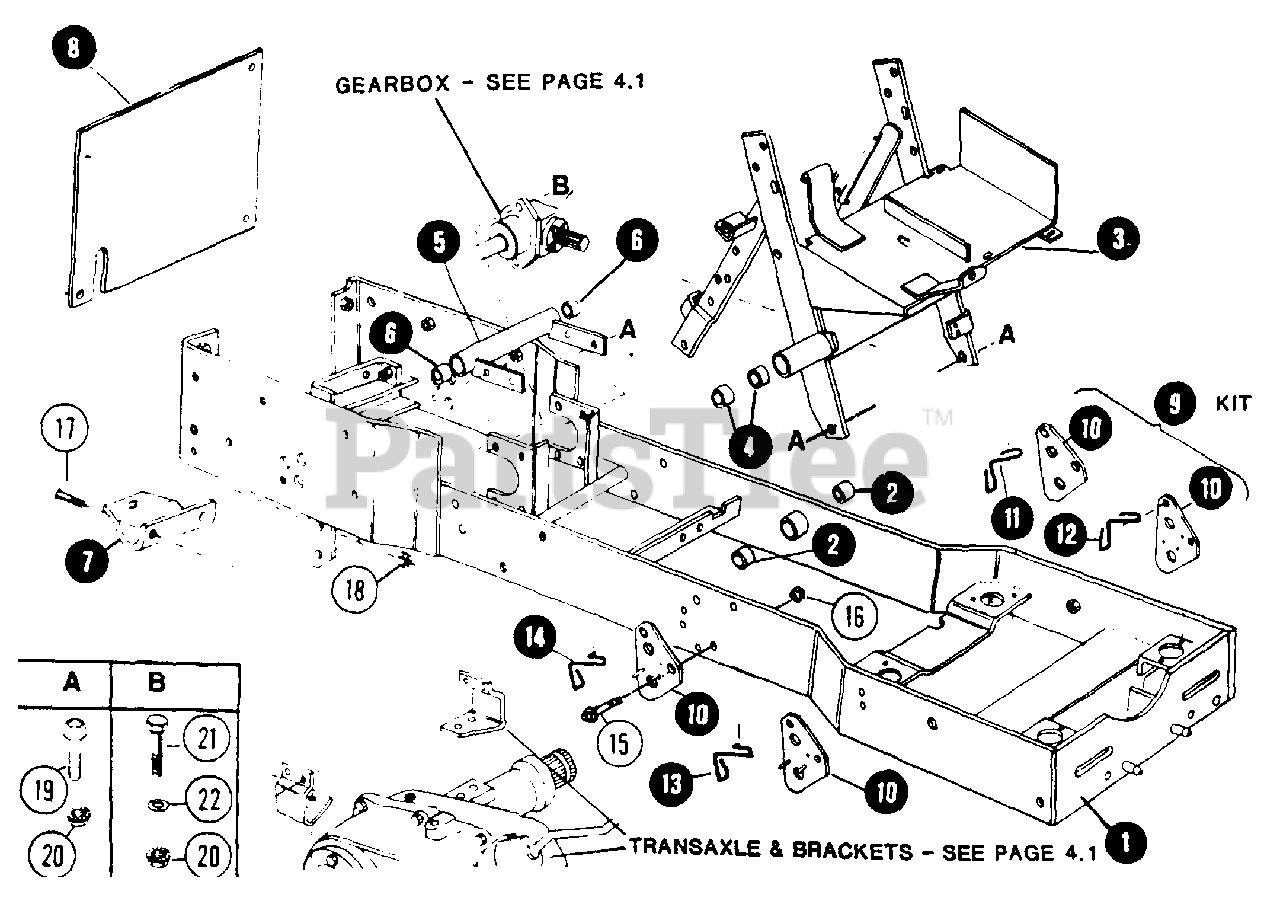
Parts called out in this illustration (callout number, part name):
1	FRAME ASSEMBLY
2	BUSHING FRAME
3	PEDESTAL FRAME ASSEMBLY
4	BUSHING, PEDESTAL
5	SUPPORT ASSEMBLY, CROSS SHAFT
6	BUSHING, CROSS SHAFT SUPPORT
7	EXTENSION, DRAWBAR
8	PLATE, FRAME REAR COVER
9	KIT, IMPLEMENT MOUNTING
10	BRACKET, LINK PIVOT
11	SPRING, LEFT REAR
12	SPRING, LEFT FRONT
13	SPRING, RIGHT FRONT
14	SPRING, RIGHT REAR
15	BOLT, 5/16-18 x 1 HEX FLANGE LOCK
16	NUT, 5/16-18 HEX LOCK
17	BOLT, 3/8C x 1" HEX HEAD
18	NUT, 3/8 HEX
19	BOLT, 3/8C X 1" HEX FLANGE
20	NUT, 3/8C HEX FLANGE LOCK
21	BOLT, 3/8C x 1-1/2 HEX FLANGE
22	WASHER, 3/8" Flat
